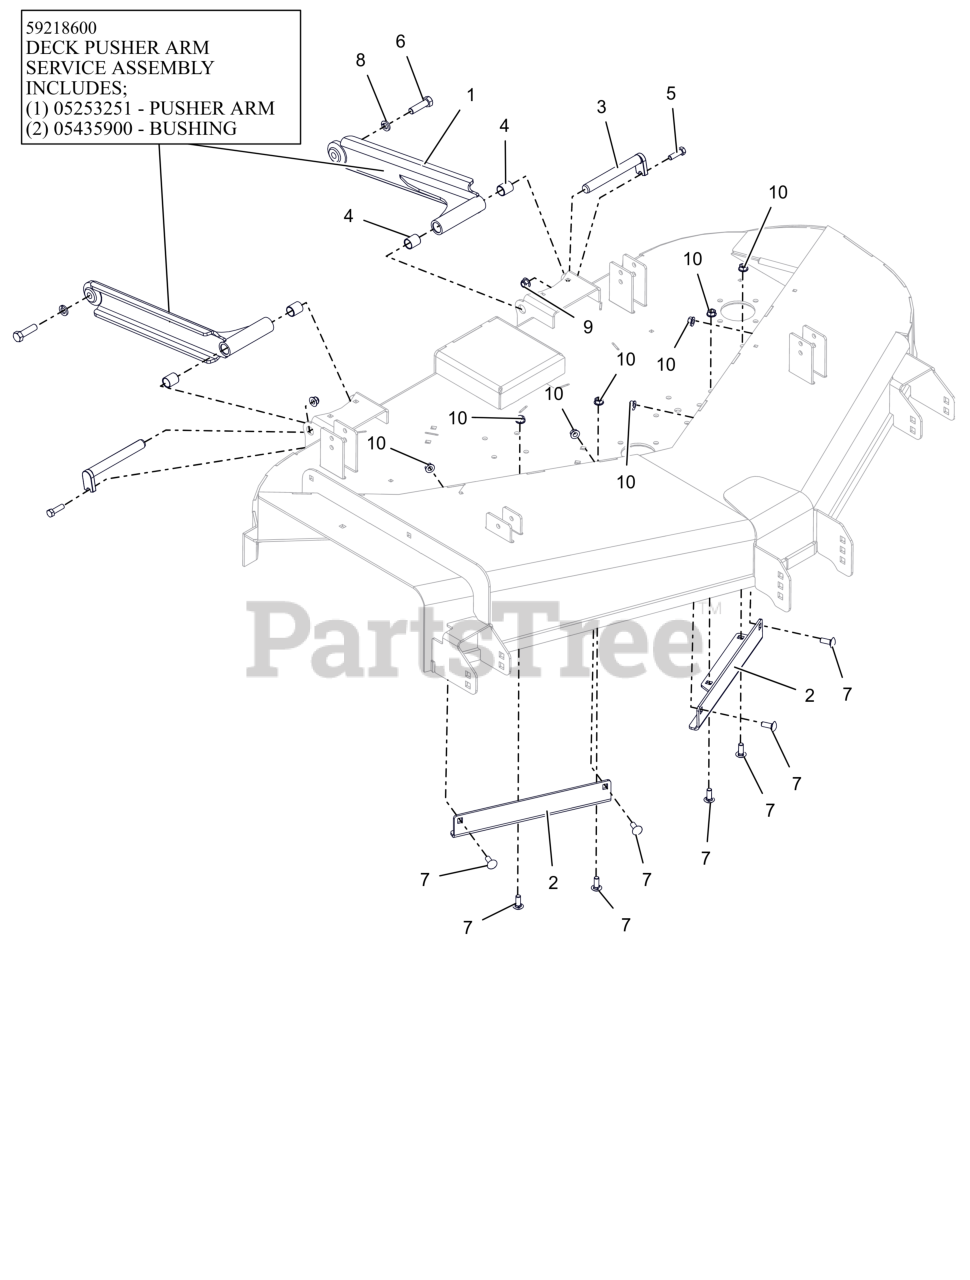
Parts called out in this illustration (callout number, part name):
1	WLDMT, DECK STABILIZER ARM (BLACK)
1	DECK STABILIZER ARM W/BUSHINGS
2	PLATE, WEAR (RED)
3	PIN, MOWER MTG
4	BRG, .750 X .875 X 1.000
5	BLT, HEX .38-16X1.25 G5 ZCC
6	BLT, HEX 0.5-13X1.75 GR5 ZCC EP80
7	BLT,RHSSN .38-16X1.00 G5 ZCC
8	WSHR,LK-REG .500X.125 ZCC
9	NUT,NYL-FLG .38-16 GF ZCC
10	NUT-LK-CTR-FLG .375-16 GF ZCC
